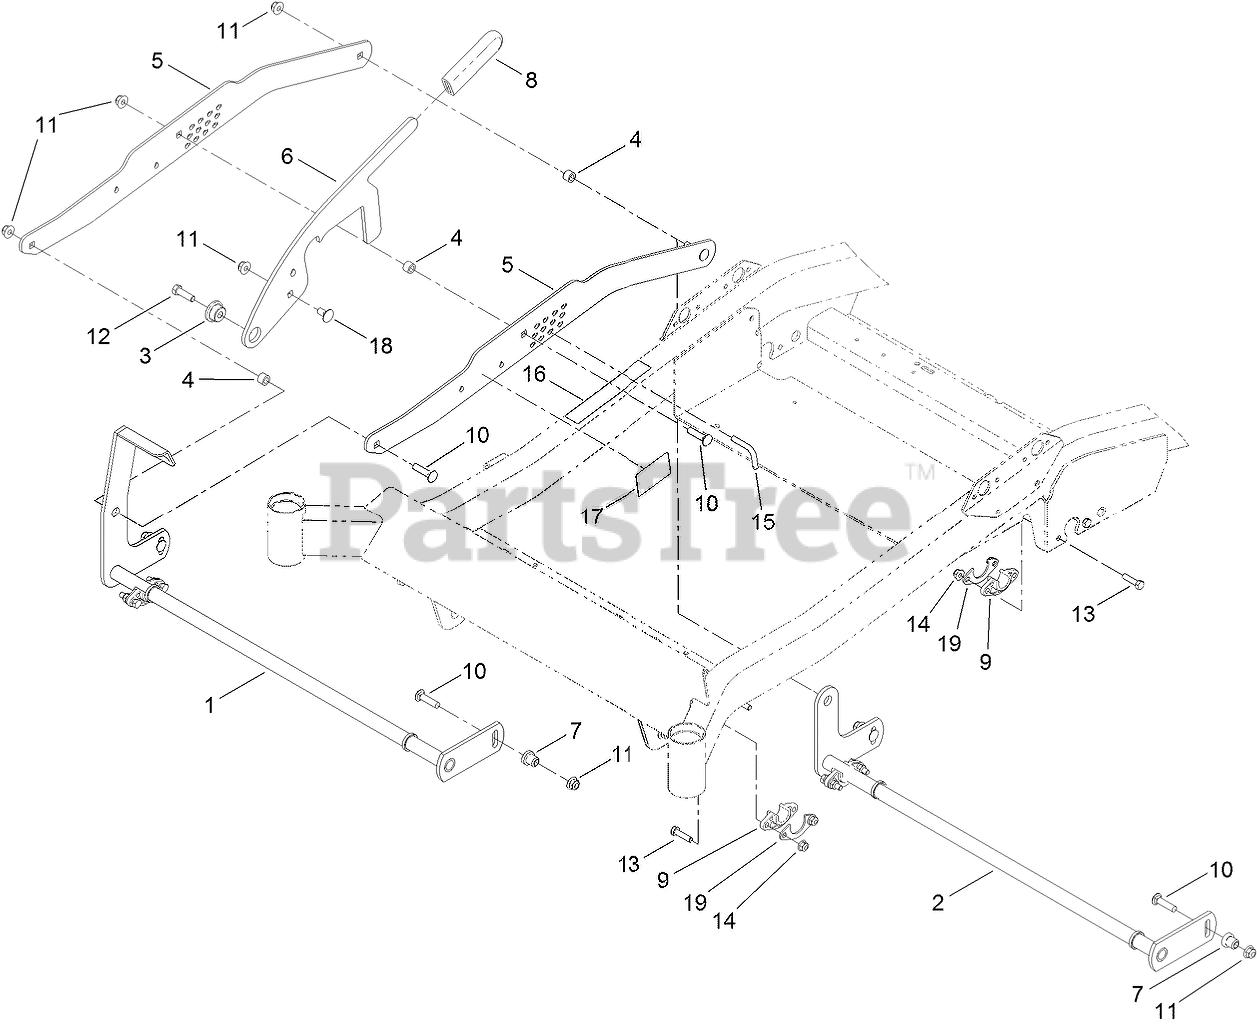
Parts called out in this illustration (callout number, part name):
1	PIVOT-FRONT
2	PIVOT-REAR
3	BUSHING-MOUNT, HOC
4	SPACER
5	PLATE-LIFT, FOOT
6	PLATE-STOP, HOC
7	BUSHING-PULLEY
8	GRIP-LEVER
9	BUSHING-FLANGE
10	SCREW-CARR
11	NUT-HF, NI
12	SCREW-HH
13	SCREW-HH
14	NUT-HF, NI
15	PIN-KEYED
16	DECAL-HOC
17	DECAL-LOCK, DECK
18	SCREW-CARR
19	GUSSET-LIFT, DECK
